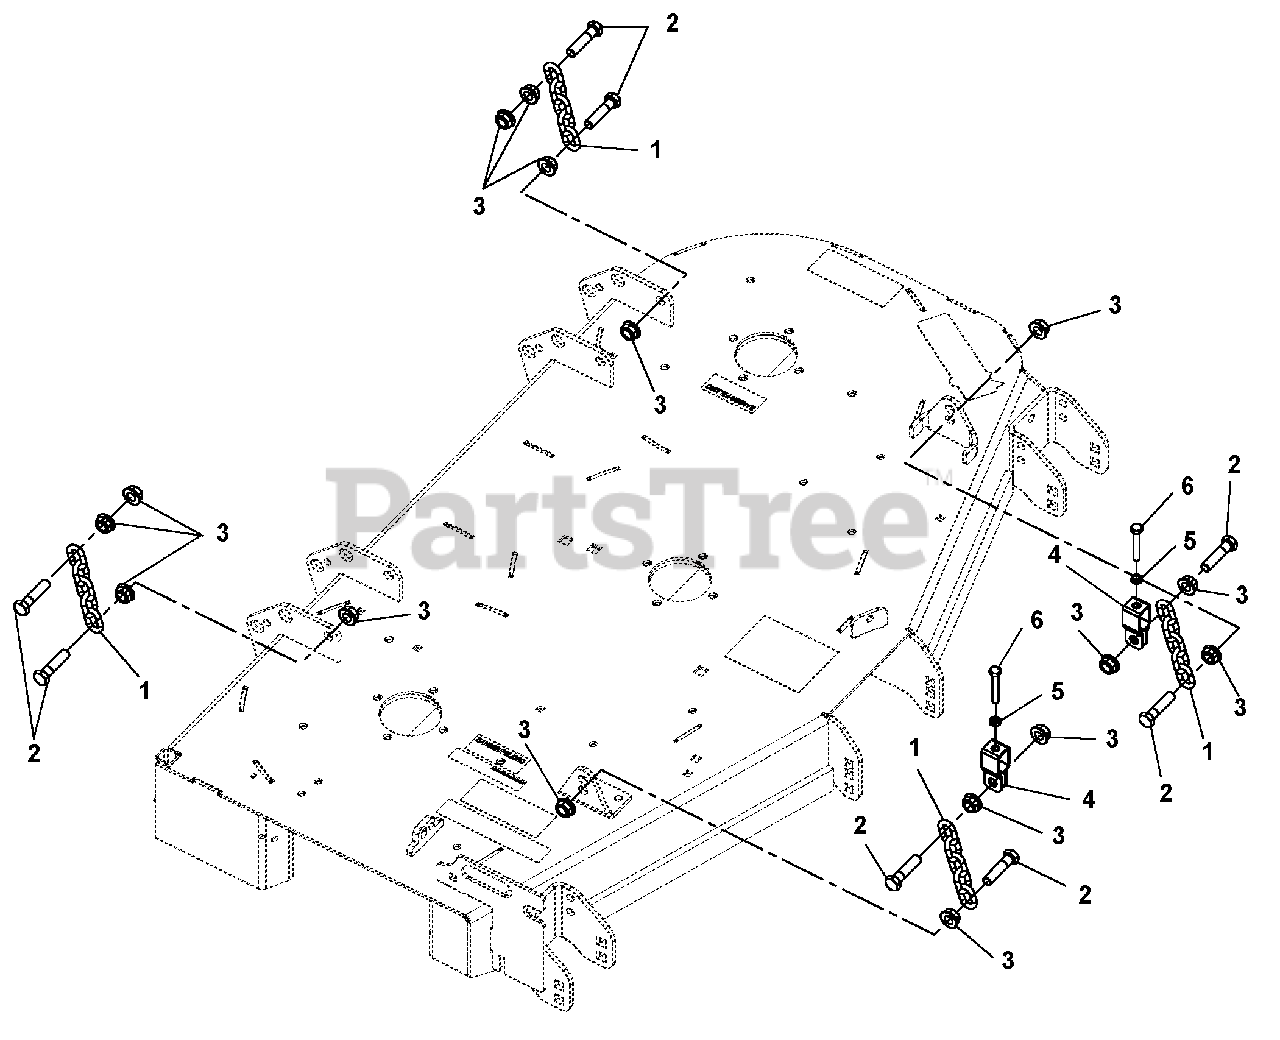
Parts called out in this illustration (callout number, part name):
1	Chain, Link
2	Bolt, Hex M12-1.75 x 50 Class 8.8
3	Nut, Spin Lock-Flange M12-1.75
4	Bracket, Deck Leveling
5	Nut, Jam .312-18
6	Bolt, Hex .312-18 x 2.00 FTH Grade 5
